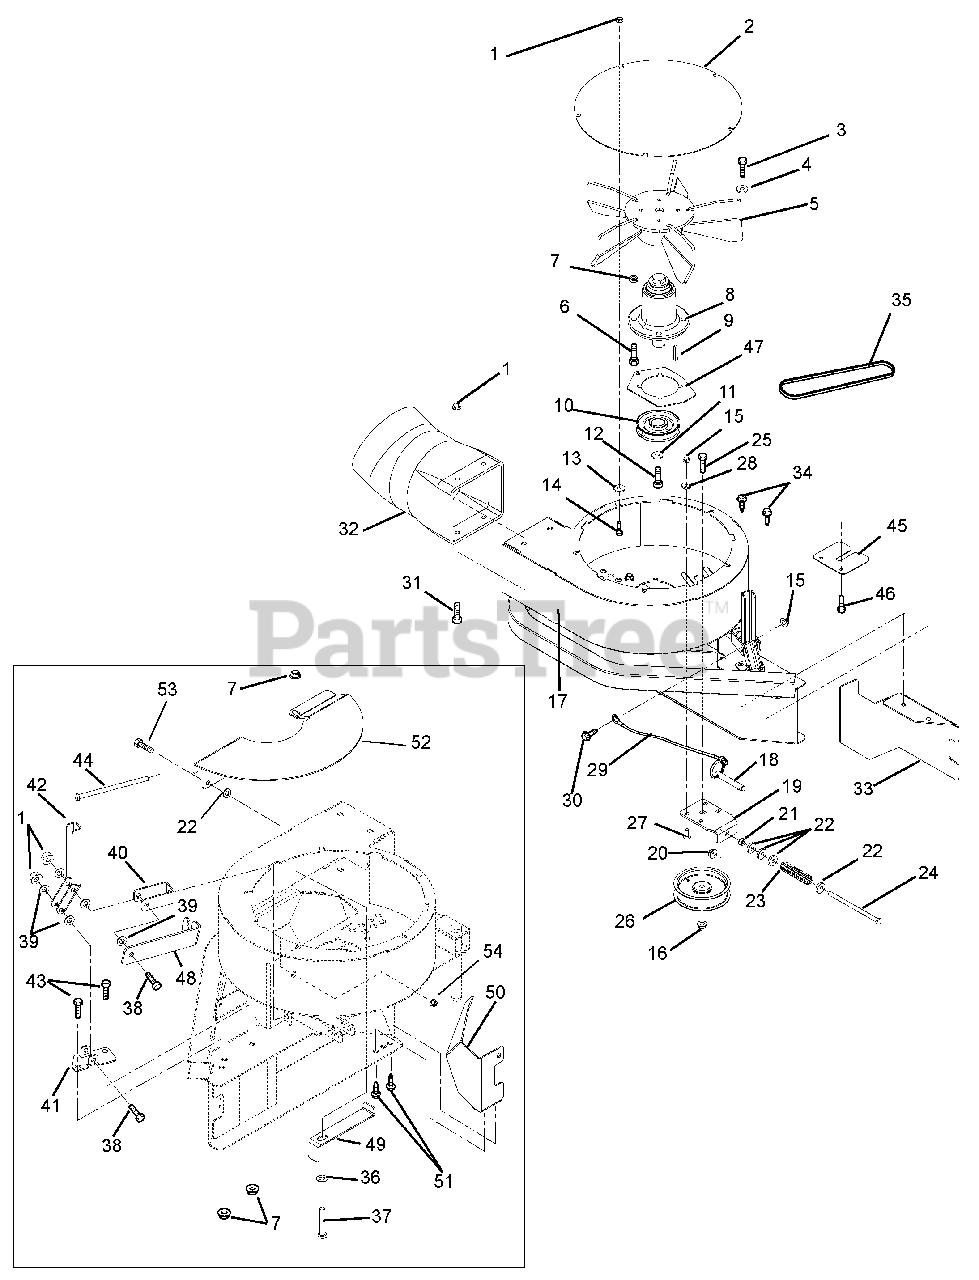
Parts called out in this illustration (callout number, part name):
1	Nut, .31-18 Nyloc Flange
2	Cover, Blower
3	Bolt, Hex .62-18 x 1.75
4	Washer, Bevelled .63 x 1.625 x .14
5	Weldment, Impeller
6	Bolt-Hex .38-16 x 1.25 Grade 5
7	Nut, .38-16 Nyloc Flange
8	Maintenance Free Spindle Assembly
9	Key, Square .25 x .25 x 1.00 RC 40-50
10	Weldment, Pulley-V 3.50 x 1.004 with Key
11	Washer, Flat Steel .39 x 1.5 x .125
12	Bolt, Hex .38-16 x 1.00 EP30
13	Nut-Push .312
14	Bolt, Round Head Square Short Neck .31-18 x .75 Grade
15	Nut, Locking-Top-Flange .25-20
16	Nut, .38-16 Nyloc Flange
17	Weldment, Blower Housing
18	Pin, Spring Ball .375OD x 1.50
19	Bracket, Adjustable Idler
20	Nut, .31-18 Nyloc Flange
21	Nut-Spin Lock-Flange .312-18
22	Washer, Flat Steel .38 x .87 x .179
23	Spring, Compression .092 x .77 x 3.13
24	Bolt, Hex .31-18 x 5.50 Grade 5
25	Bolt, Hex .38-16 x 1.75 Grade 5
26	Pulley, Idler 4.00
27	Bolt, Round Head Square Neck .25-20 x .75 Grade 5
28	Bushing-Flange .265 x .437 x .250 x .750
29	Cable, Hood
30	Bolt, Hex .25-20X.75 Grade 5
31	Bolt, Hex .31-18X.75 Grade 5
32	Adapter, Hose
33	Baffle, Blower 52"
34	Screw, Tapping .38-16 x .50 Hex Washer Head
35	V-Belt, 72" Mower Deck
36	Washer, Flat - Steel .406 x .812 x .065
37	Bolt, Hex .38-16 x 1.00 Grade 5
38	Bolt, Hex .31-18 x 2.00 Grade 5
39	Washer, Flat-Nylon .375 x .75 x .060
40	Link, Idler Release
41	Mount, Idler Release Lever
42	Lever, Idler Release
43	Bolt, Hex .38-16 x .75 Grade 5
44	Bolt, Hex .31-18 x 5.50 Grade 5
45	Finger Guard 52-Inch Deck
46	Bolt, Hex .25-20 x .50 Grade 5
47	Plate, Bearing Housing Support
48	Lock, Idler Release Lever
49	Finger, Belt
50	Baffle, Blower Rear 52"/60"
51	Screw, Tapping .38-16 Hex Washer Head Thread Rolling
52	Cover, Bottom Plate
53	Bolt, Hex .31-18 x 0.75
54	Nut, Nyloc Flange .31-18
